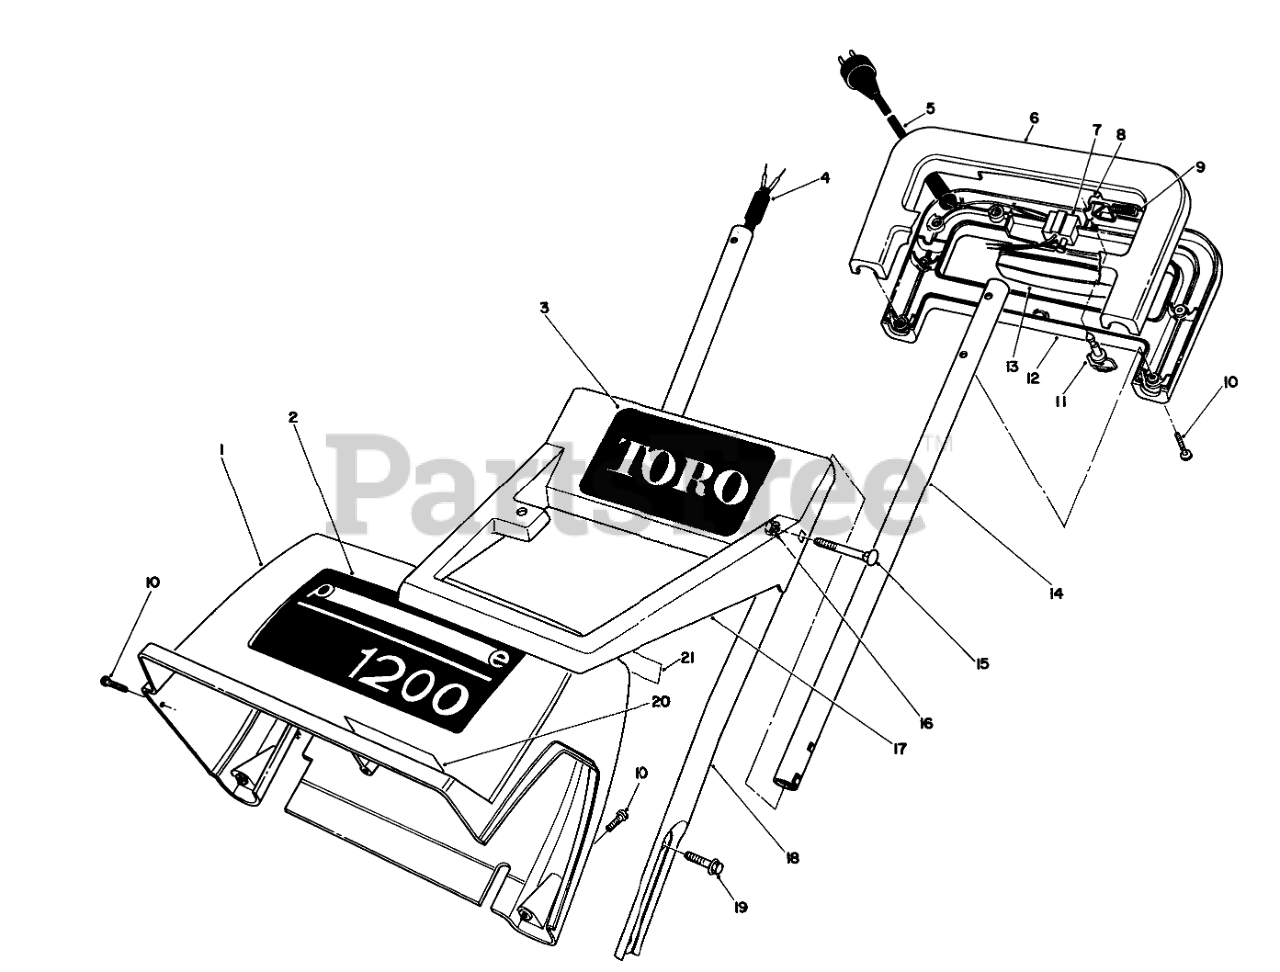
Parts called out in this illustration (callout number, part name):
1	Shroud (Incl. Ref. #2, 20, & 21)
2	DECAL-TORO 1200
3	DECAL-TORO
4	WIRE HARNESS
5	SUPPLY CORD, 1200
6	1200PC-CONTROL HANDLE U
7	SWITCH-STARTER
8	LOCKOUT, 1200
9	COMP SPRING
10	Screw
12	1200 P CONTROL HANDLE L
13	SWITCH BAR, 1200 PC
14	UPPER TUBE, S-120
16	NUT-LOCK, NI
17	MIDDLE HANDLE, 1200
18	LOWER TUBE, LH, S-120
19	Screw
20	DECAL, DANGER
21	Decal-U.L.
